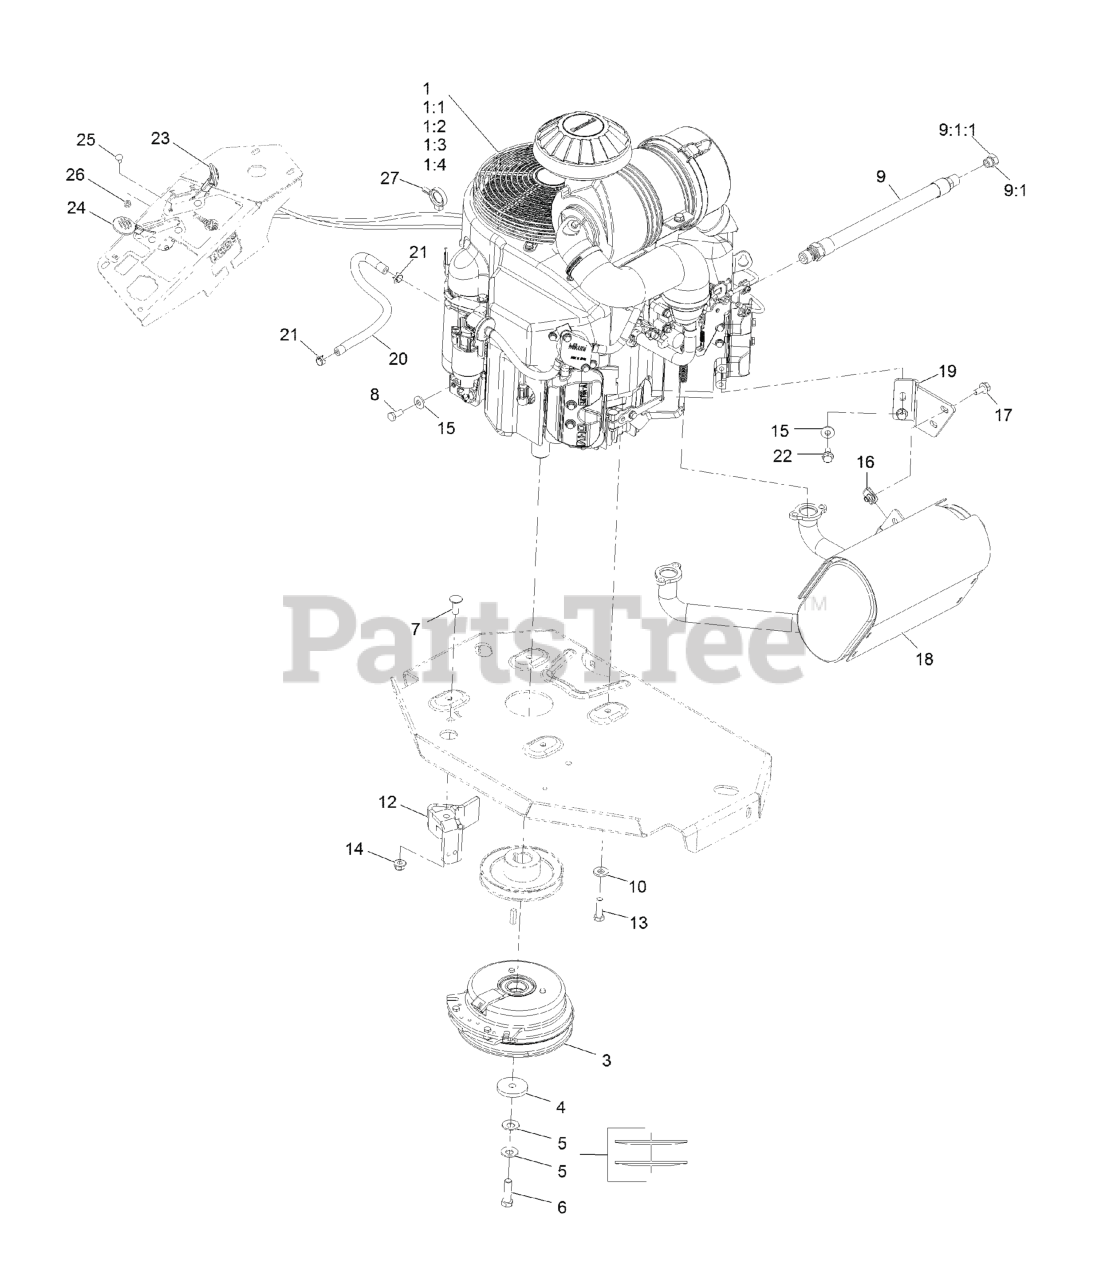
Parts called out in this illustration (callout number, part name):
1:1	Kawasaki 49065-2078 Engine Oil Filter
1:2	Kawasaki 49019-7001 Fuel Filter
1:3	Kawasaki 11013-7039 Safety Filter
1:4	Kawasaki 11013-7038 Air Filter
3	CLUTCH KIT
4	WASHER-CLUTCH
5	WASHER-SPRING
6	SCREW-HH 7/16-20 X 1 1/2 W/LOCTITE
7	SCREW-CARR
8	SCREW-HH
9	ENGINE OIL DRAIN HOSE ASM
9:1	PLUG-HH
9:1:1	O-RING
10	WASHER-BELLEVILLE
12	CLUTCH-ANCHOR
13	SCREW-HH
14	NUT-HF, NI
15	WASHER-SPRING
17	SCREW-HHF
18	MUFFLER
19	BRACKET-MUFFLER
20	HOSE-FUEL
21	CLAMP-HOSE
22	SCREW-HHF
23	ASM, CHOKE CABLE
24	ASM,THROTTLE CABLE
25	BOLT-CARR
26	NUT-LOCK, NI
27	CLAMP-HOSE
